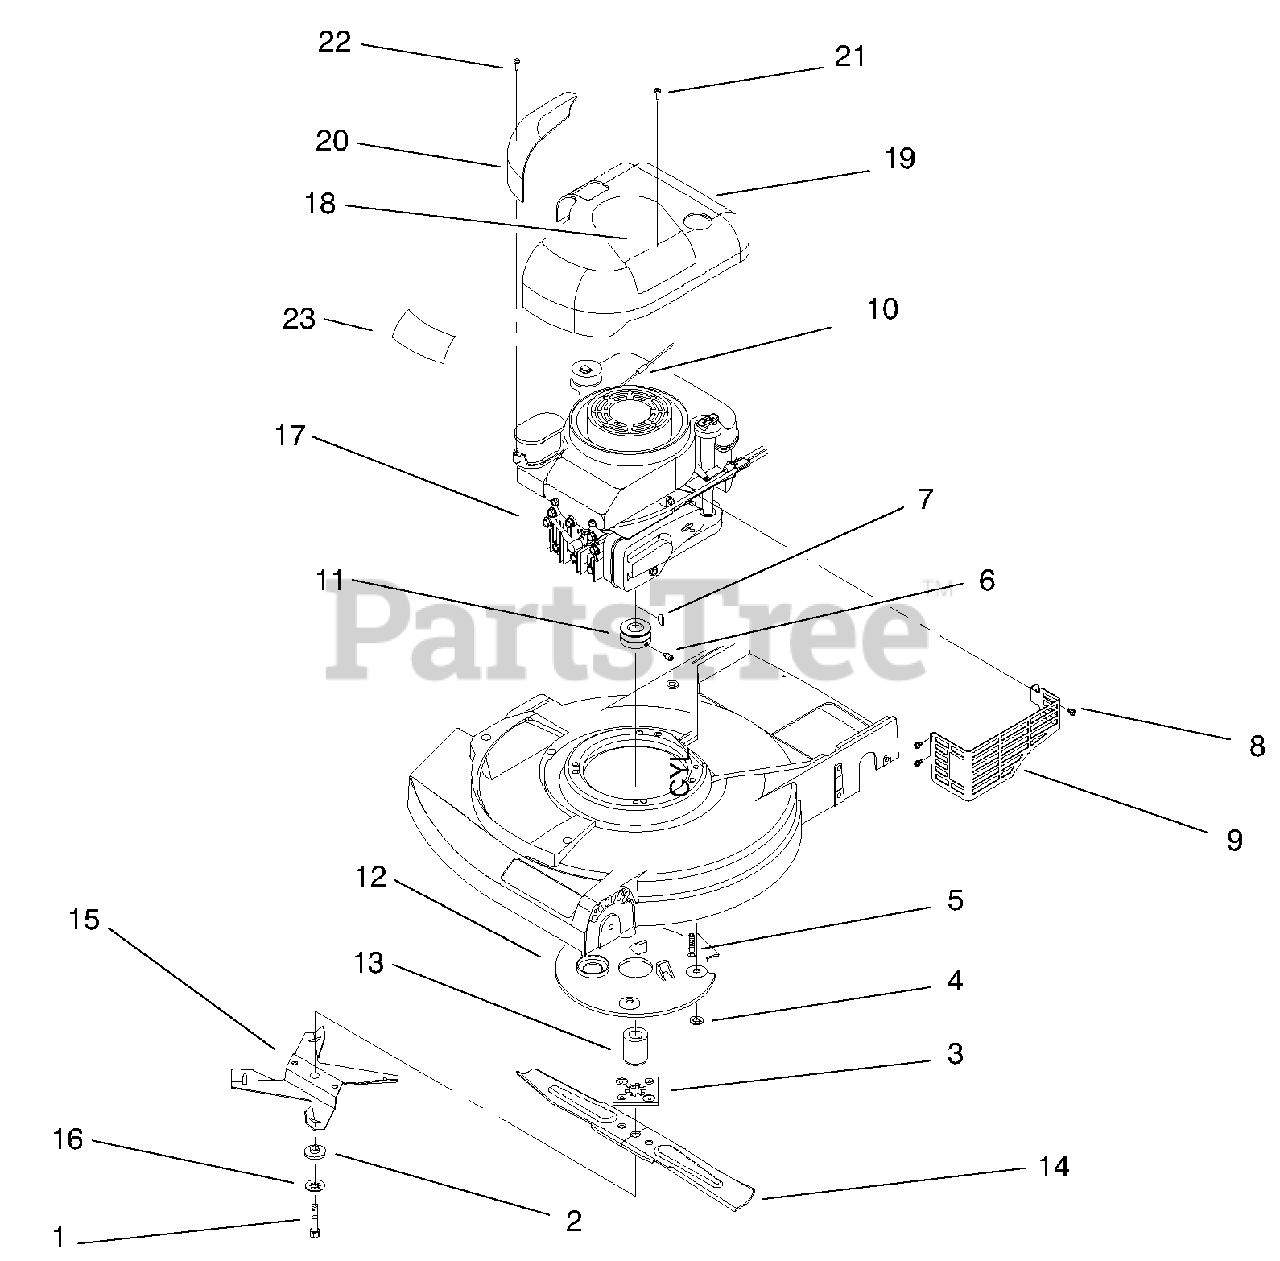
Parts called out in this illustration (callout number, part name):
1	Bolt-Blade
3	Plate-Blade Driver
4	Nut-Push
5	Screw-Engine Mount
6	Screw-Set
7	Key-Woodruff
8	Screw-HWHTF
9	Shield-Muffler
10	Rope-Stop (P/W Eng)
11	Pulley-Engine
12	Shield-Grass
13	Hub-Blade Driver
14	Blade-21" Whirl
15	Fan-Mulching
16	Washer-Lock
17	Engine-4 Cycle
18	Decal-Recoil
19	Shroud-Engine (P/W Eng)
20	Cover-Air Cleaner (P/W)
21	Screw-Shroud (P/W Eng)
22	Screw-Air Cleaner (P/W)
23	Applique
